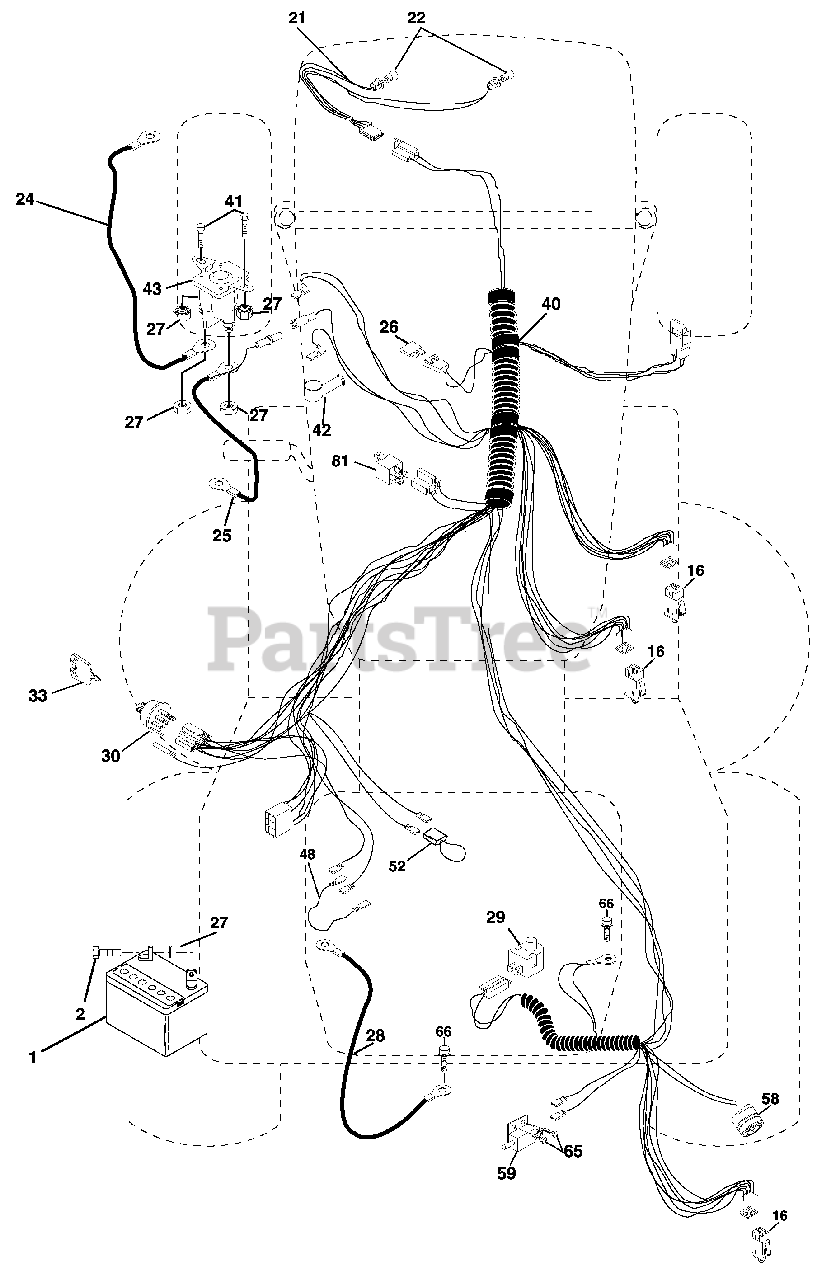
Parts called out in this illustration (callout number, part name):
1	Battery 12 Volt 25 AMP Wet
2	Bolt Hex Hd 1/4-20 Unc X 3/4
16	Switch Interlock Push-In
21	Harness Asm Light W/4152J
22	Bulb Light #1156
24	Cable Starter 6Ga 11" Red
25	Cable Battery Crd 56" Red
26	Fuse 15 Amp
27	Nut Keps Hex 1/4-20 Unc
28	Cable Ground 6Ga 18" Black
29	Switch Plunger Normal Op Olive
30	Switch Ignition
33	Key Ign Molded
40	Harness Ign Crd Noram
41	Bolt Flk Fin Hex 1/4-20 Unc X 1/2
42	Cover Terminal Red
43	Solenoid
48	Adapter Ammeter Rectangular
52	Protection Wire Loop
58	Buzzer Crd
59	Switch FBI CRD
65	Screw Slftp #10-16 x 1/2 Ty-Ab
66	Screw Thdrol 3/8-16 x 1/2 Ty-Tt
